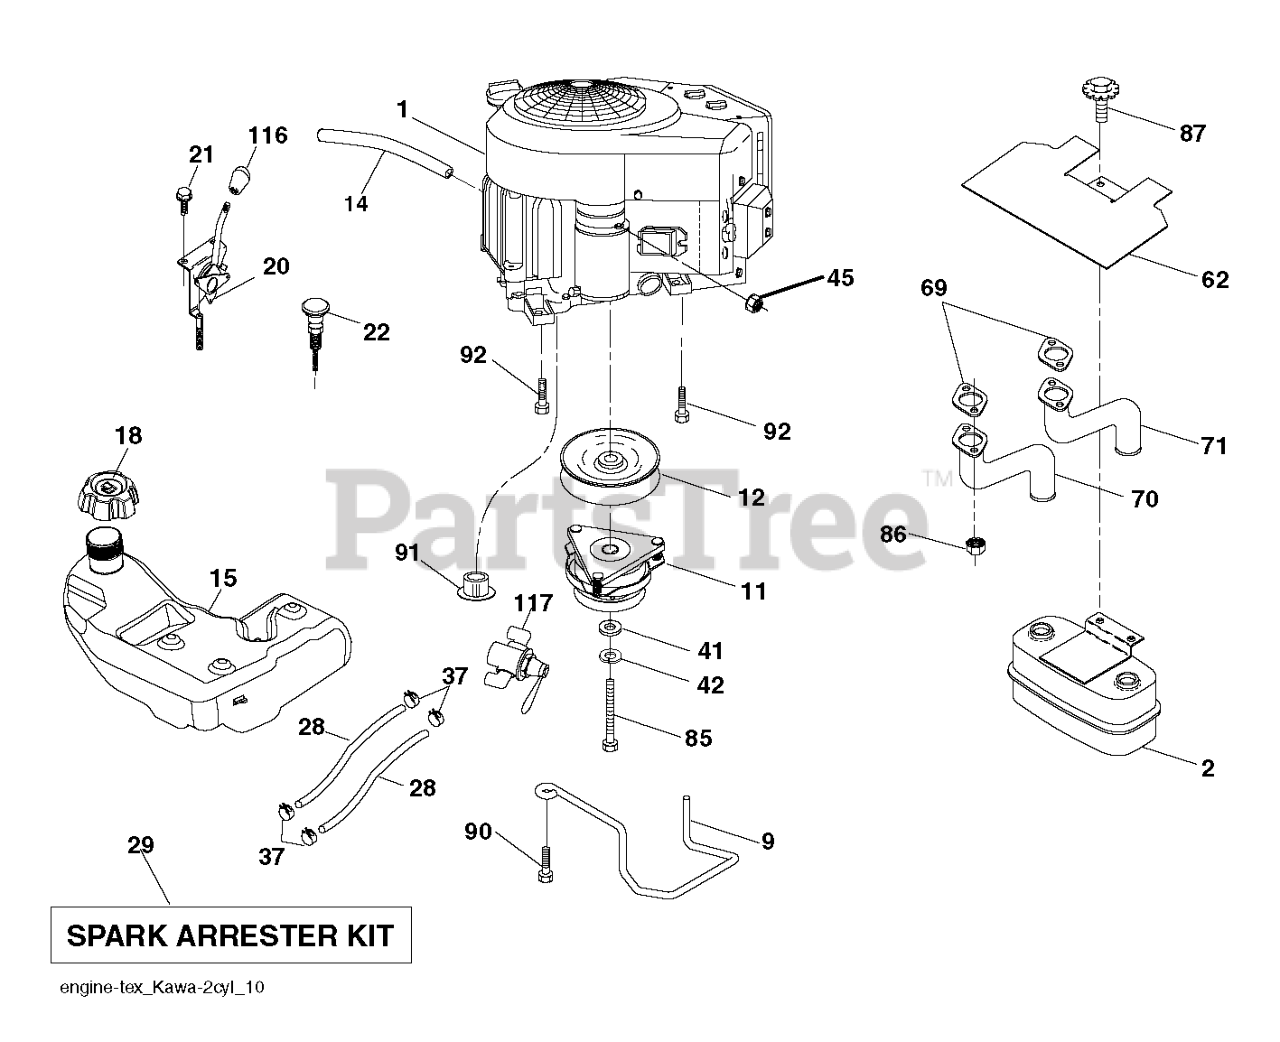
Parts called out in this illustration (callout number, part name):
2	MUFFLER.TWIN.CYL.LOW.TONE
9	KEEPER.BELT.ENGINE.4.2
11	CLUTCH.ELECTRIC.LT.48"*
12	PULLEY.ENGINE.TUFFTORQ
14	TUBE, DRAIN OIL ASM.
15	RP_TANK.ASSY.4.GAL.2.PORT.EPA
18	CAP.ASM.FL.RITCH.3"E10.SYM.498
20	CONTROL.THROTTLE.PRO.
21	SCREW.#10 X 0.750.BOS
22	CONTROL.CHOKE.ERGO.PUSH-IN.BLA
28	LINE.FUEL.64"REAR.EMIS
29	KIT.SPARK ARRESTOR 794945 B&S
37	HOSE CLAMP
42	LOCKWASHER
45	NUT
62	SHIELD.HEAT.MUFFLER
70	TUBE.EXHAUST.LH.FR961/FR730
71	TUBE.EXHAUST.RH.FR961/FR730
85	BOLT HEX 7/16-20X4-1/4"
86	NUT.HEX.FLANGE.TOPLOCK
87	BOLT 5/1618UNC X 3/4 W/ SEMS
90	SCREW 3/8-16X1
91	BUSHING.1.375OD
92	SCREW 3/8-16X1
116	RP KNOB SOFT TOUCH
117	VALVE FUEL RESERVE
